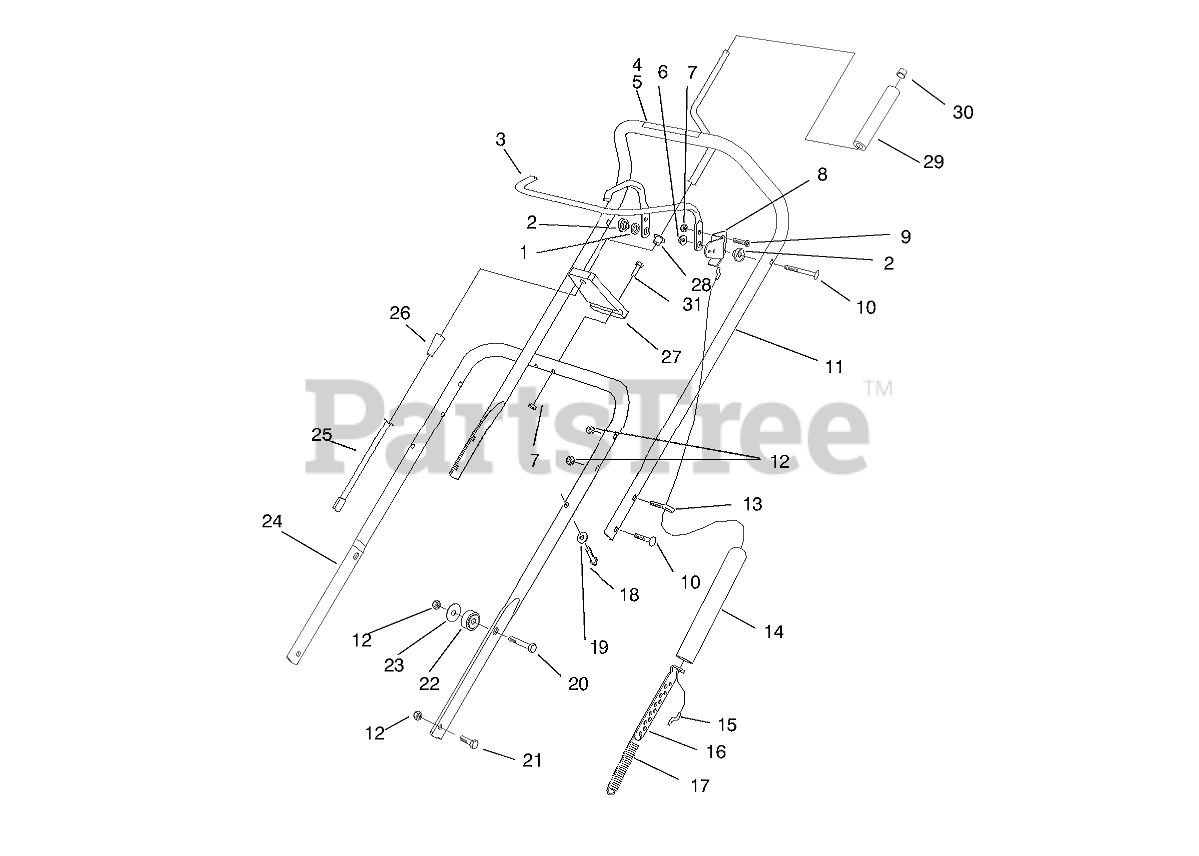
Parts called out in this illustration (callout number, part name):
1	WASHER
2	SPACER-BAR, CONTROL
3	Bar-Control
4	DECAL - ROTOR DRIVE
5	DECAL-DRIVE, ROTOR
6	NUT-LOCK, CAP
7	NUT-LOCK, NI
8	Arm-Clutch Cable
9	SCREW-HSBH
10	SCREW
11	Handle-Upper
11	UPPER HANDLE W/DECAL
11	UPPER HANDLE ASM
12	NUT-LOCK, NI
13	BOLT-EYE
14	COVER-SPRING
15	CABLE-CLUTCH
16	ADJUSTER-CABLE
17	SPRING-EXTENSION
18	SCREW
19	WASHER
20	SCREW-HH
21	SCREW-HH
22	SPACER - LOWER HANDLE
23	WASHER-FLAT
24	Handle-Lower
25	ROD-CRANK, CHUTE
26	SPRING-COMPRESSION
27	Support-Crank
28	Bushing
29	GRIP-CONTROL, CHUTE
30	RETAINER-PUSH ON
31	SCREW-HH
